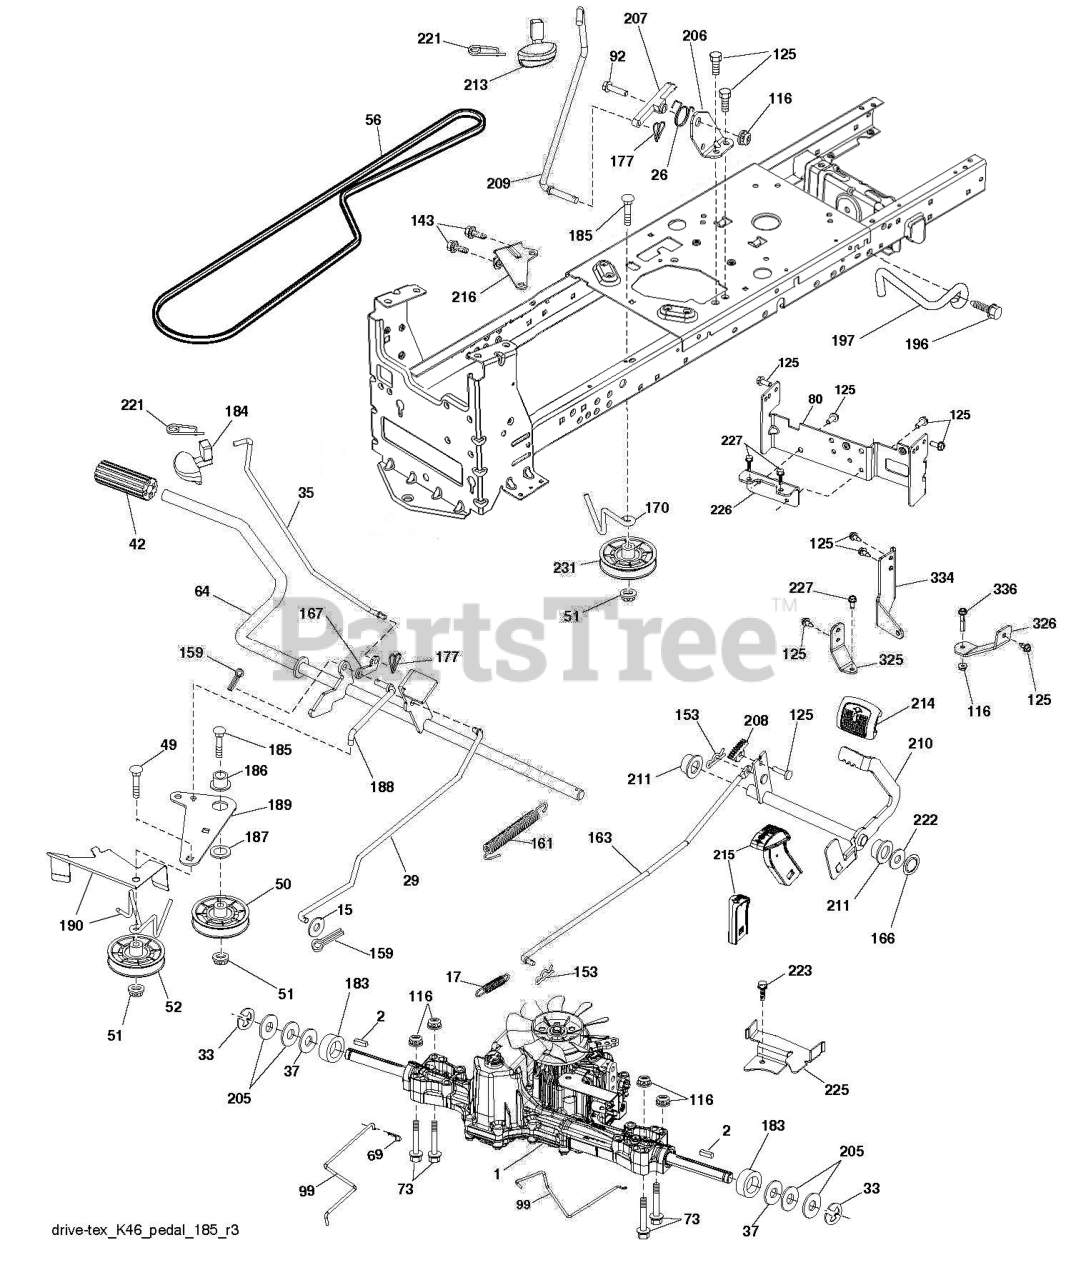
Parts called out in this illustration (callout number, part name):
2	SQUARE KEY
15	WASHER
15	WASHER PLAIN WASHER 3/8 X 0.08
17	SPRING.BRAKE.K46.GREEN
26	SPRING.RETURN.CRUISE
29	ROD.BRAKE.K46
35	Rods
35	ROD ROD.PARKINGBRAKE.GT.HUSQ/P
37	WASHER.HARDENED
42	PEDAL COVER
49	BOLT
50	IDLER.FLAT.910.OFFSET
51	NUT LOCK FLG 3/8-16 UNC
52	IDLER.V-GROOVE.910.OFFSET
56	V-BELT.MOWER.92.40.42/K46
64	SHAFT.ASM.PEDAL.BRK.CNTR
69	HAIRPIN.SOFT.ZINC.059X1.125
73	BOLT
80	STRAP TORQUE
99	ROD.SPRING.BYPASS.K46.LT.Z
99	ARM.PIVOTING.TCRD.GEN2.5.BAGGE
116	NUT LOCK HEX FLANGE 5/16-18
125	SCREW
153	RETAINER M
159	COTTER PIN
161	SPRING, RETURN LT
166	NUT.PUSH.625
167	LATCH.BRAKE.SPRING
170	KEEPER.CENTER SPAN.1.688
177	GSPW Retainers
177	PIN COTTER;LOCKING;BOWTIE;1IN
183	SPACER AXLE
184	HANDLE.PARKING.BRAKE.H (BLK)
186	SPACER.RETAINER
188	LINK.CLUTCH.GROUND DRIVE.LONG
189	BELLCRANK.GROUND.DRIVE.TEX.
190	KEEPER.BELLCRANK.DRIVE
196	SCREW 3/8-16X1
197	CLUTCH.ANTIROTATION.WIREFORM.
197	LINK.CLUTCH.ANIT-ROTAT
206	BRACKET.MOUNT.CRUISE.LATCH
207	LATCH.CONTROL.CRUISE
209	ROD.CONTROL.CRUISE.GT.
209	Rods
209	ROD ROD.CRUISECONTROL.GT.HUSQ/
210	ROCKER.ASM.PEDAL.CONTR
211	BEARING.NYLON
213	KNOB.CONTROL.CRUSIE.HU
214	PEDAL.FORWARD.PAD.TEX
215	PEDAL.REVERSE.TEX.GT.4
215	PEDAL.COVER.REVERSE.CRD.X428BK
216	BRACKET.PULLEY.IDLER.W/TEX
221	RETAINER.SPRING.CLIP.H
222	WASHER 21/32 X 1-1/4 X 10 GA.
223	SCREW
225	KEEPER.BELT.TRANSAXLE.K46
226	BRACKET.MOUNT.TORQUE.K46.TLT
227	Bolts
227	SCREW HEXAGON HEAD SCREW 5/16-
231	IDLER.V-GROOVE.1.688.OFFSET
325	TORQUE.STRAP.K46.LT.LH
326	BRACKET.TRQ.STP.K46.18"TIRE.RH
326	BRCKT.PNT.TRQ.STP.46.18TIRE.RH
334	SWAY.ROD.BRACKET.K46.X431
336	Bolts
336	GSPW Nuts
336	BOLT.5/16-18X1-3/4.FLANGED.HEX
